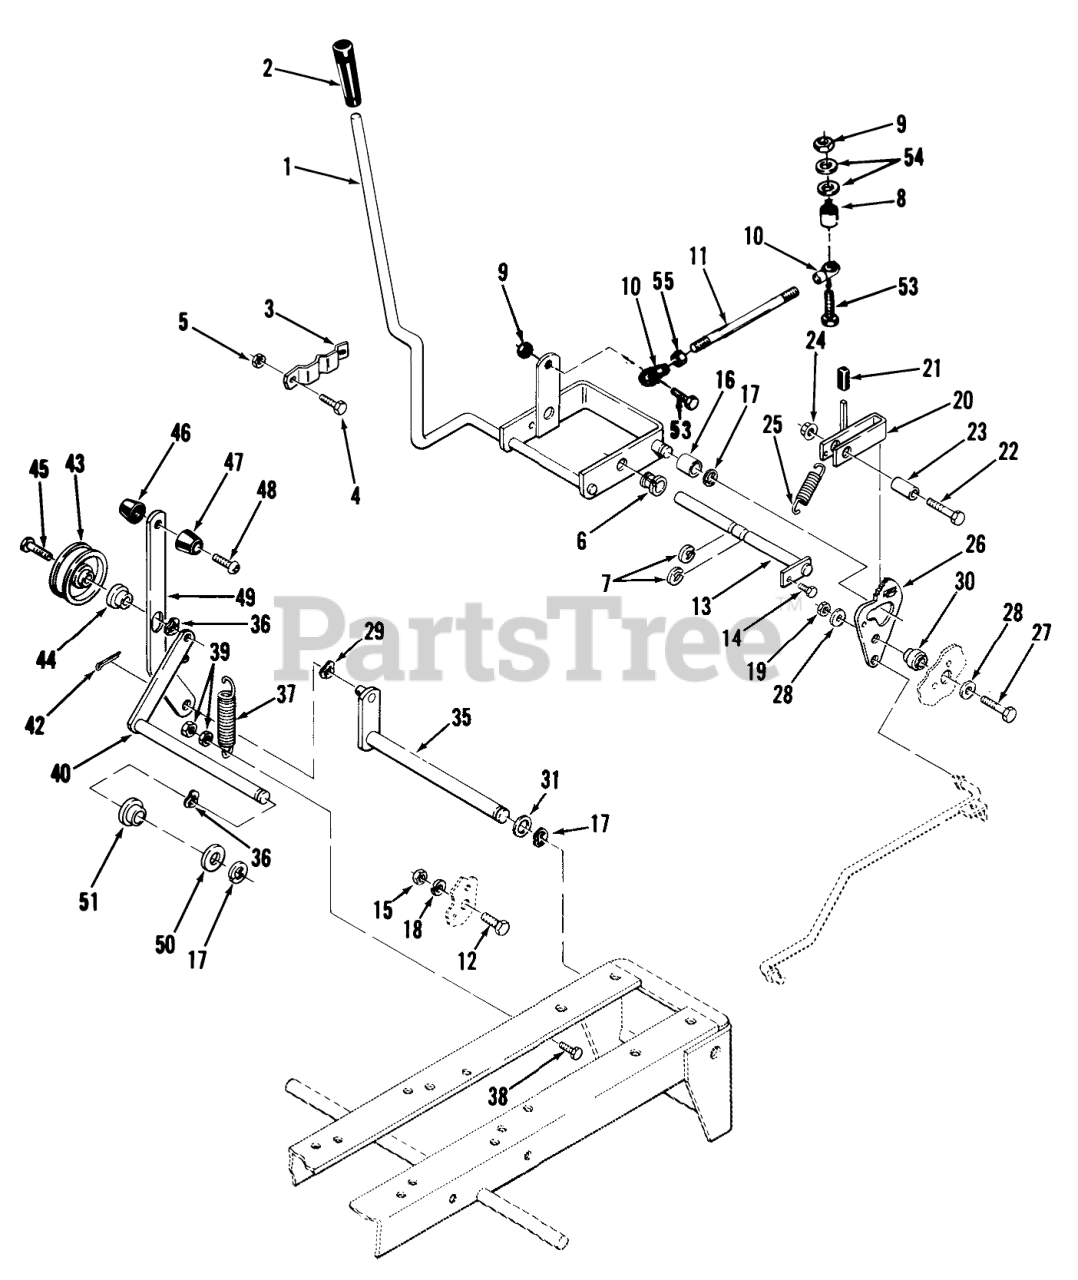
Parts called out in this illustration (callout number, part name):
1	Motion Control Lever
2	KNOB
3	Detent-Motion Control Lever
4	H H C S
5	Nut
6	NYLINER BUSHING
7	E Ring
8	Spacer
9	Nut
10	Rod End
11	ROD-CONTROL
12	BOLT
13	ASSY-ROD CAM PIVOT
14	SCREW
15	Nut
16	BEARING-CAM RETURN
17	E Ring
18	LOCKWASHER
19	Nut
20	PAWL HDL ASSY B
21	VALVE LEVER GRIP
22	BOLT
23	SPACER
24	LOCKNUT-FLANGE
25	Spring
26	Cam Plate
27	Bolt
28	Washer
29	WASHER-WAVE
30	Spacer
31	Washer
35	ASSY-BRAKE LEVER
36	WASHER-WAVE
37	SPRING-EXTENSION
38	Bolt
39	Nut
40	ASSY-ARM/ROD WA
42	Cotter Pin
43	Idler Pulley
44	SPACER-BRAKE LINK
45	BOLT-SPECIAL HEX
46	KNOB
47	KNOB
48	BOLT-4
49	Handle
50	Washer
51	BUSHING-FLANGED
53	Bolt 1/4-20 X 1 1/2
55	Jam Nut 1/4-28
